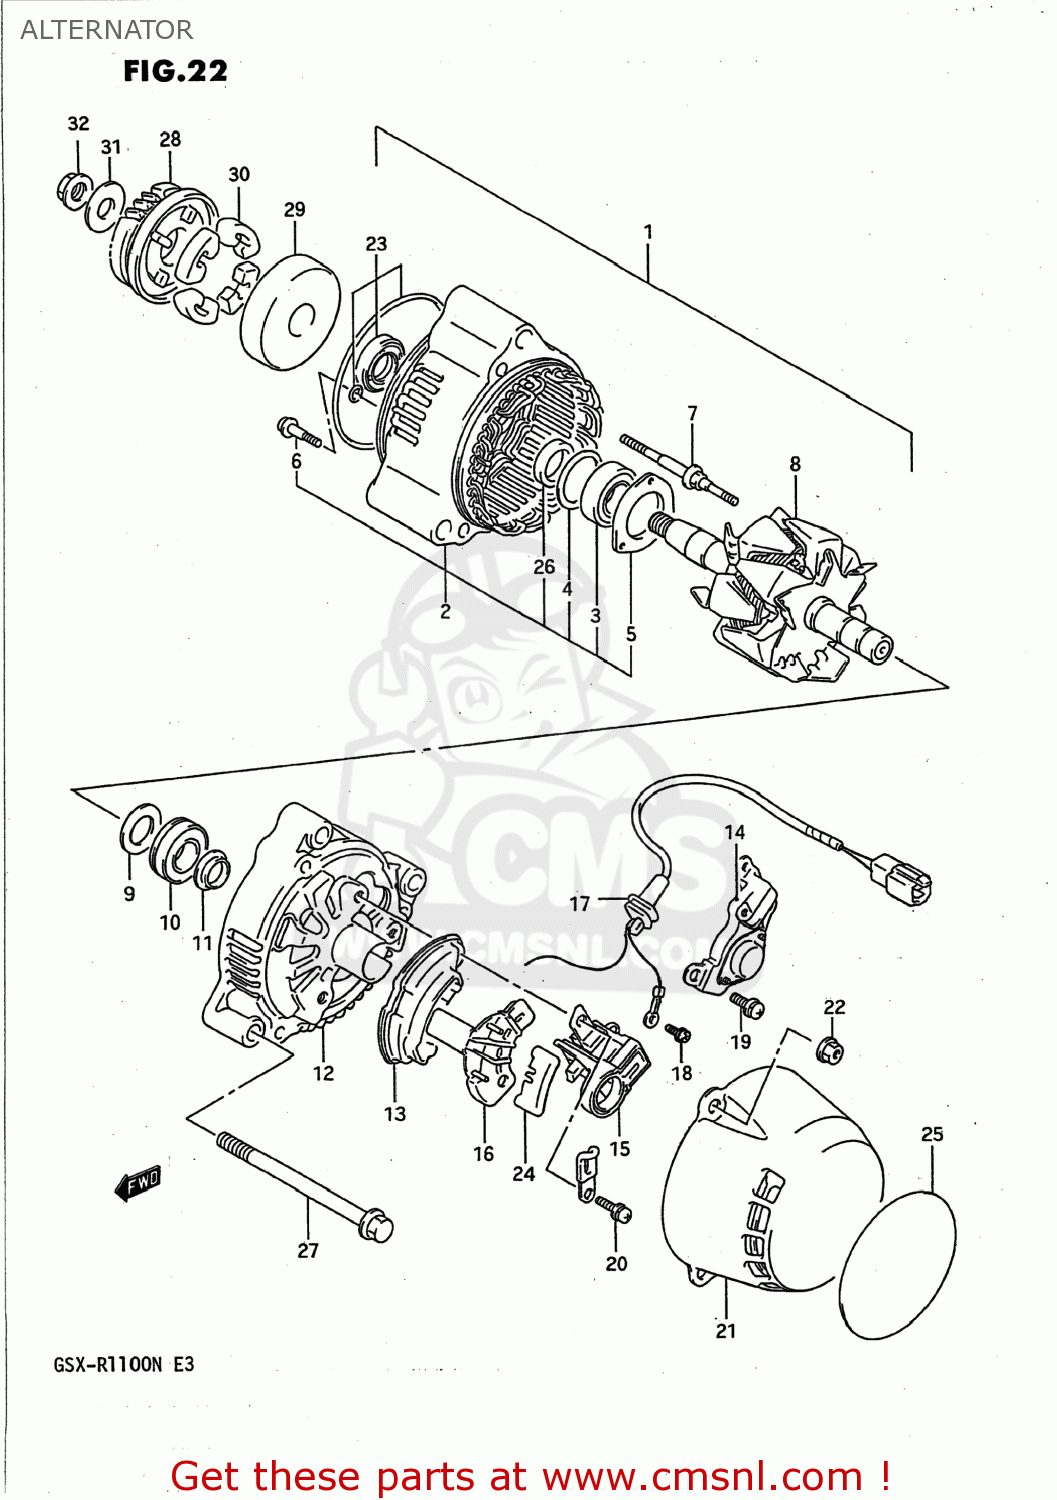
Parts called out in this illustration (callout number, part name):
1	GENERATOR ASSEMBLY
2	FRAME,DRIVE END
3	BEARING
4	COVER,BEARING
5	RETAINER
6	SCREW,BEARING RETAINER
7	STUD BOLT
8	ROTOR ASSEMBLY
9	COVER,BEARING
10	BEARING
11	COVER(2)
12	FRAME,END
13	HOLDER,RECTIFIER
14	REGULATOR
15	HOLDER,BRUSH
16	COVER,RECTIFIER
17	WIRE,LEAD
18	SCREW
19	SCREW
20	SCREW
21	COVER
22	NUT ,5MM
23	SEAL SET,OIL
24	BUSH
25	PROTECTOR,ALTERNATOR
26	SPACER
27	BOLT 8X90
28	GEAR,GENERATOR DRIVEN
29	HOUSING,GENERATOR GEAR
30	DAMPER,GENERATOR DRIVEN
31	WASHER
32	NUT
